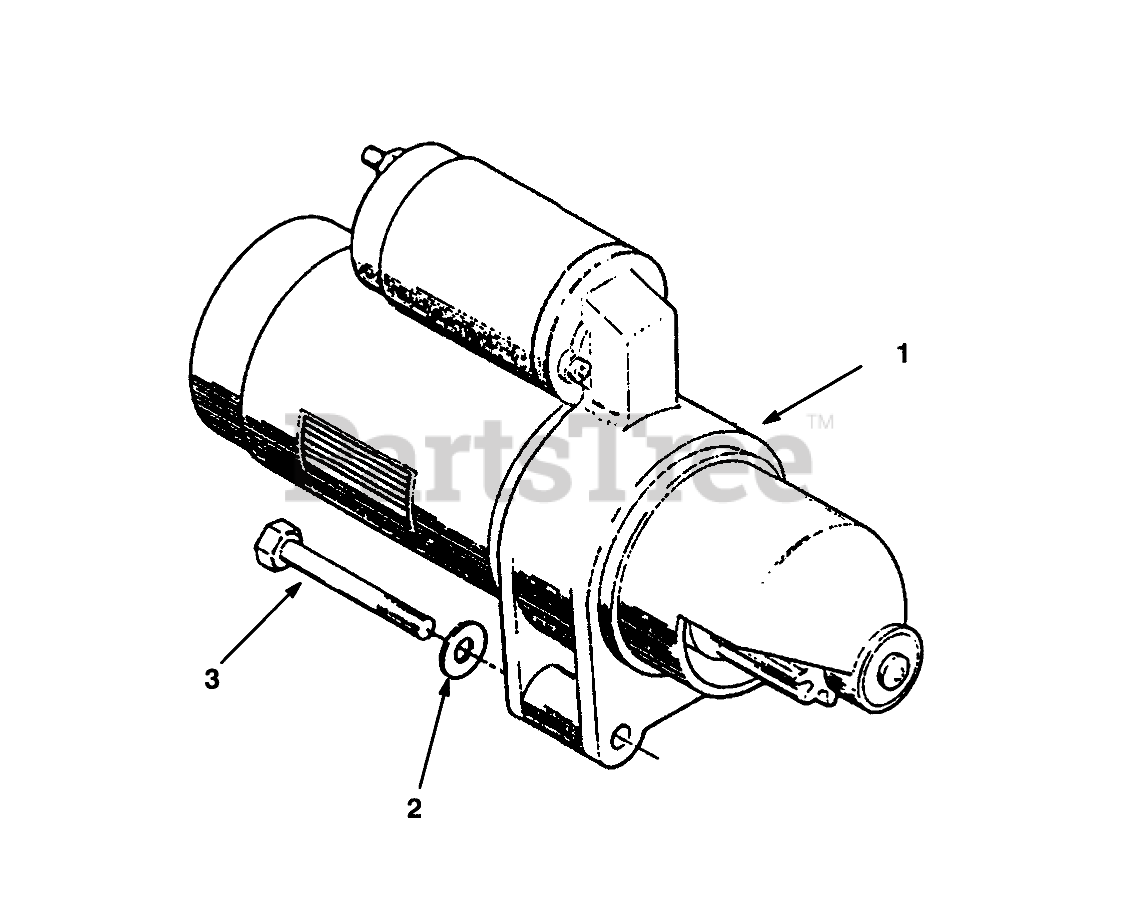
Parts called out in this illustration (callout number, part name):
1	STARTER
2	Washer
3	SCREW
